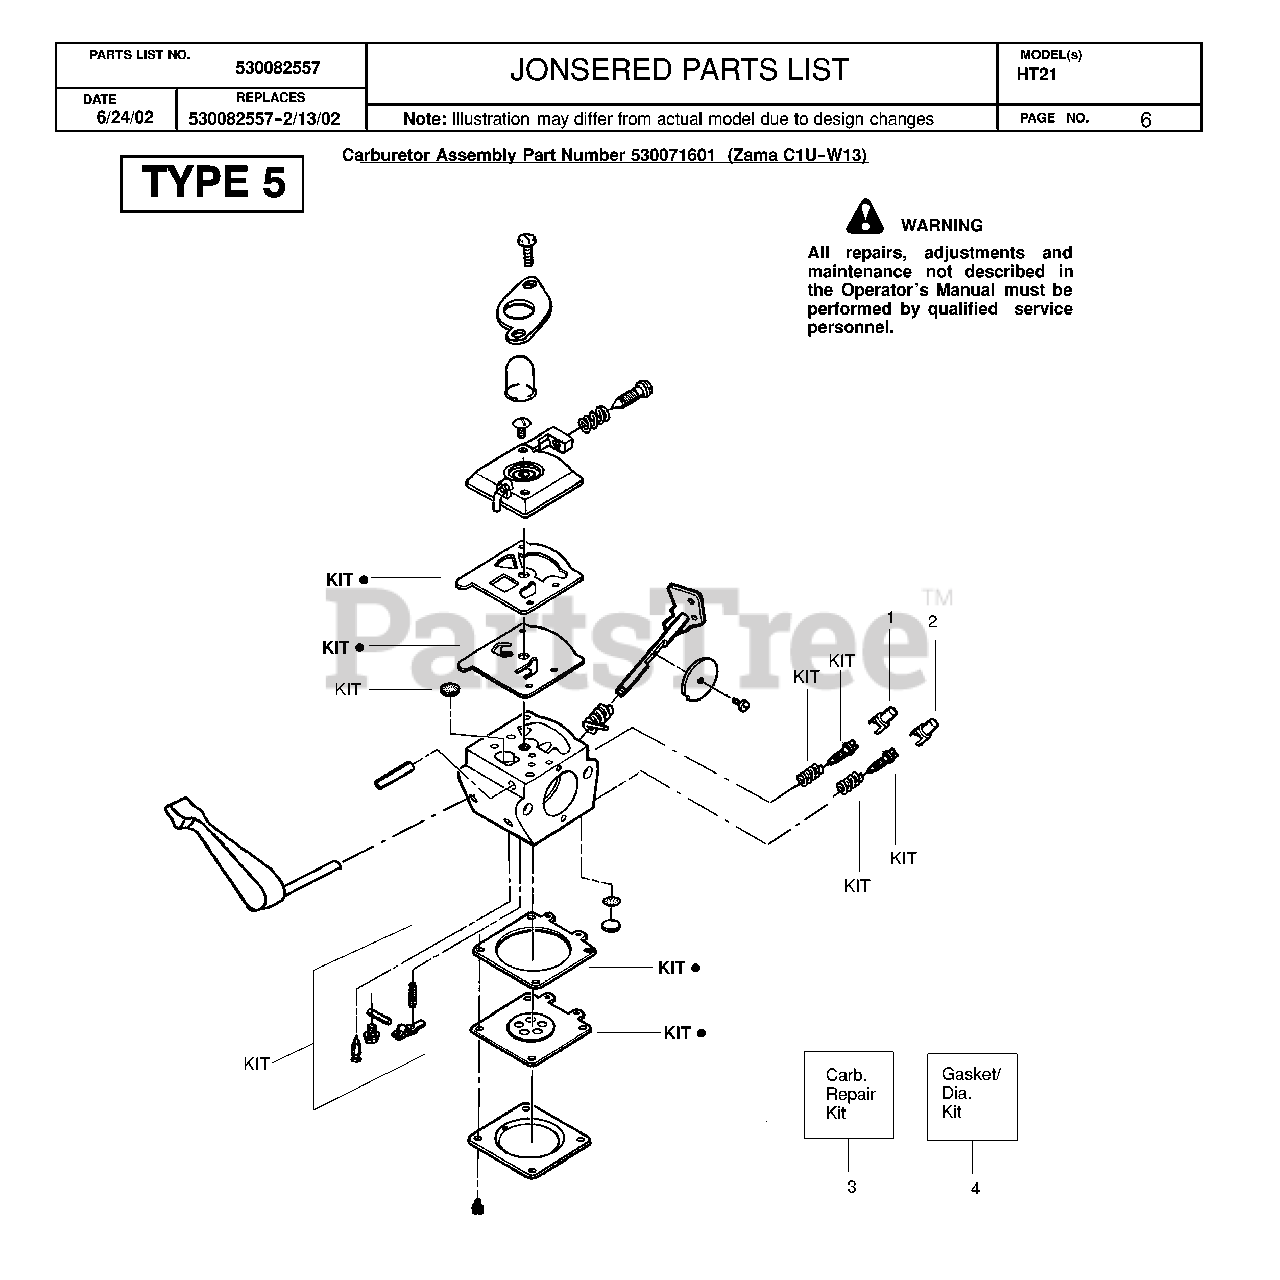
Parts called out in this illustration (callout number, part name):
1	LIMITER CAP-LOW
2	LIMITER CAP-HIGH
3	CARBURETOR REPAIR KIT
4	GASKET/DIAPHRAGHM KIT
